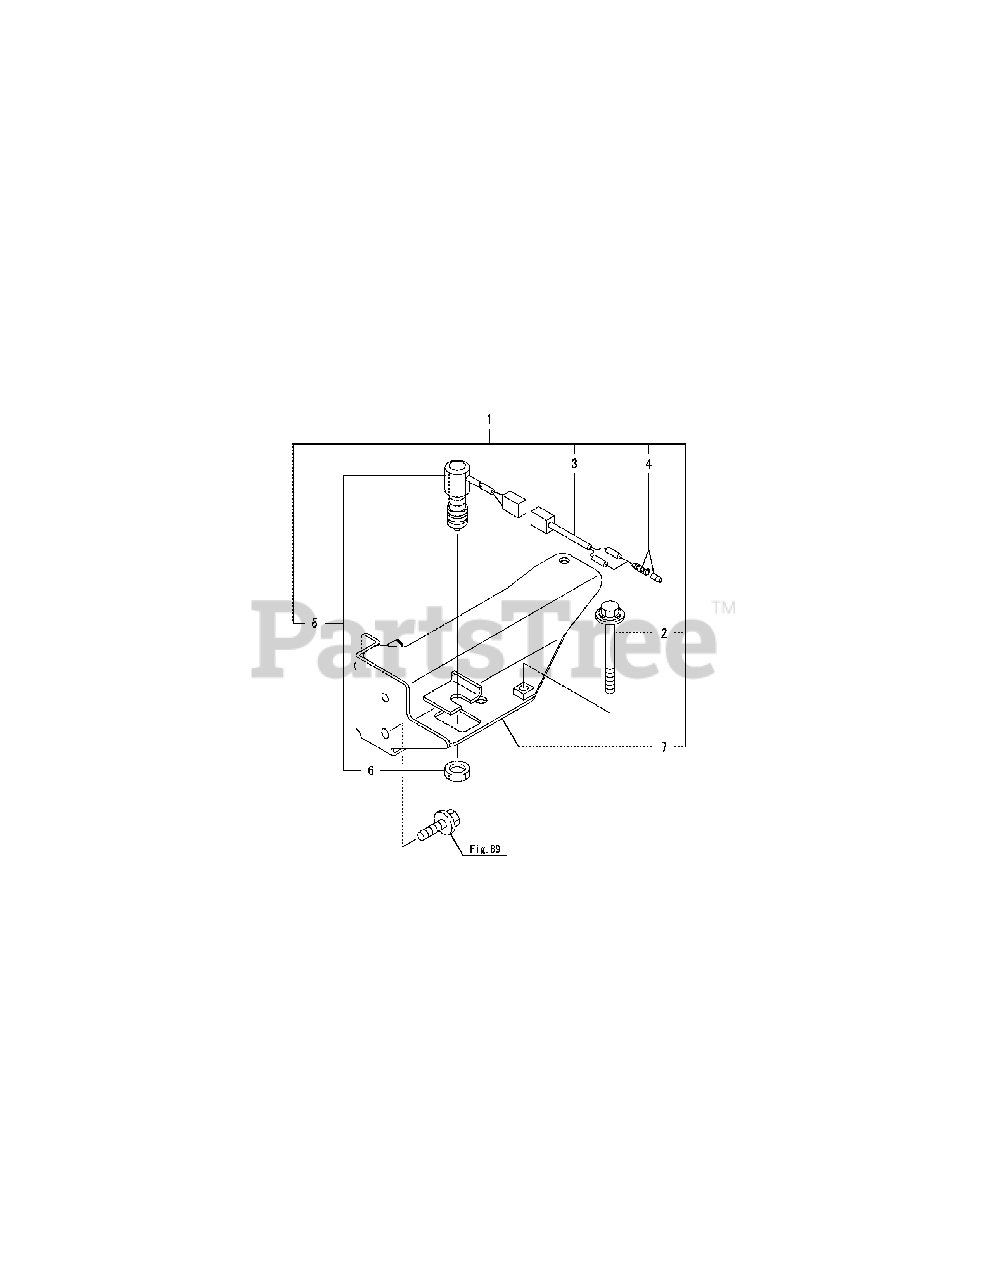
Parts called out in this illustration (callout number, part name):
1	Cable Kit, Brake Sw.
2	Bolt, Hst Pedal
3	Cable, Brake Sw.
4	Terminal, Bullet Ca10
5	Switch, Brake Lamp
6	Lock Nut M12 Plated
7	Stay Assy, Rf Step
